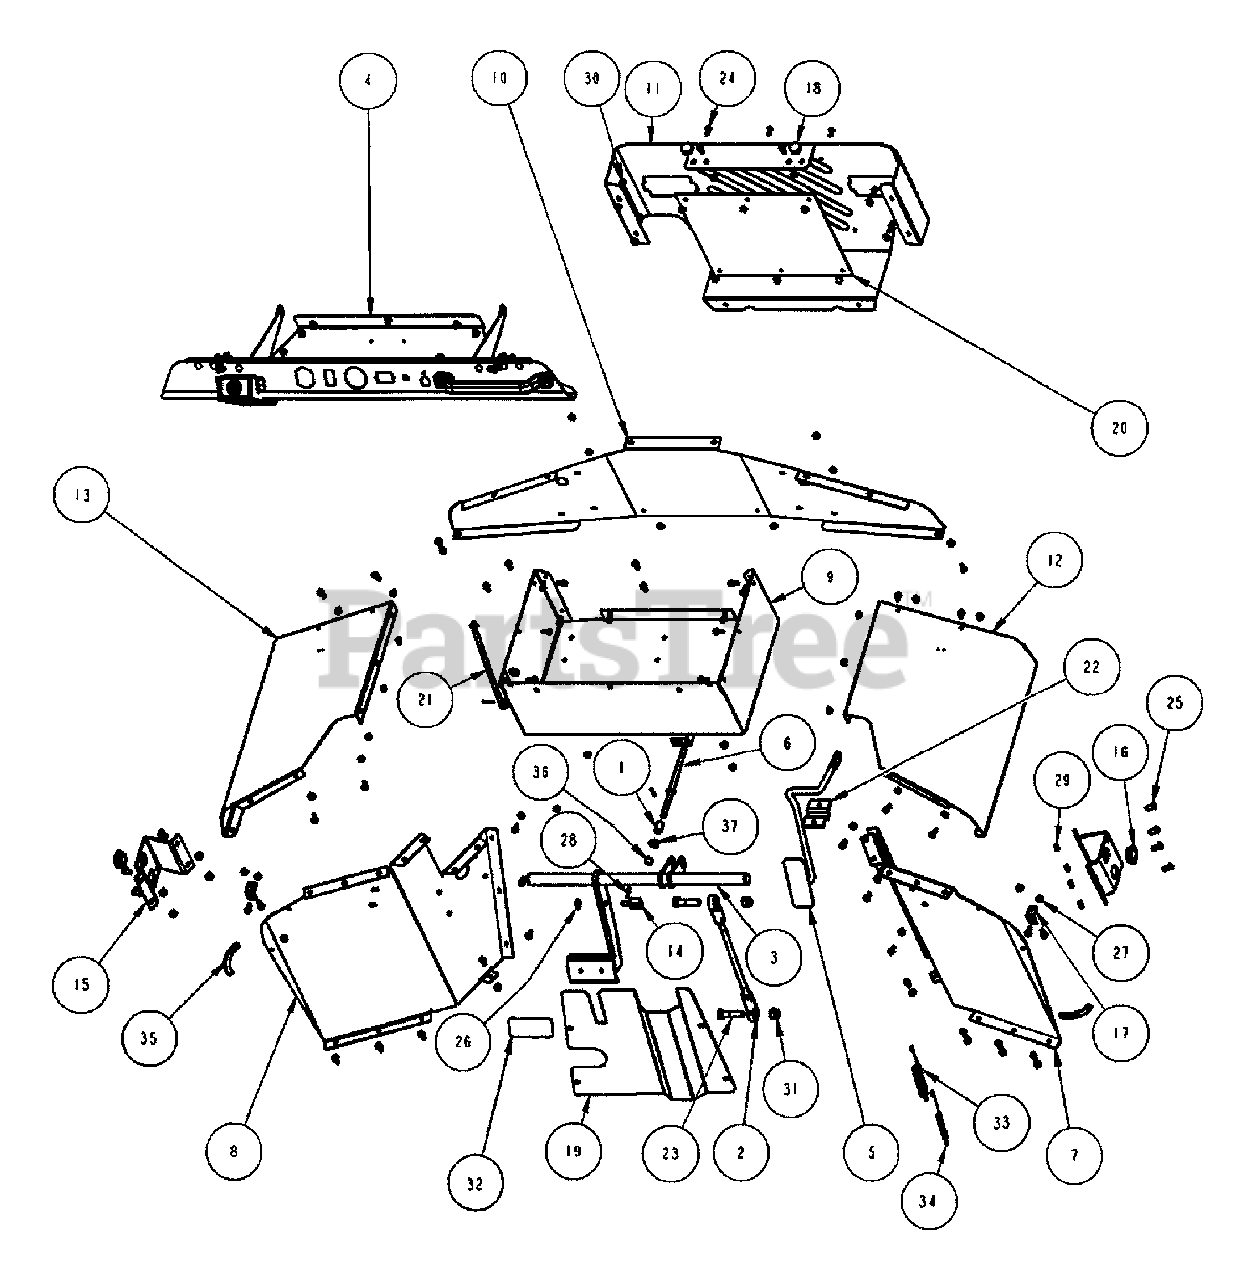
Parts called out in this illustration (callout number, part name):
1	SPRING, .051 WD X .46 OD X 2FL
2	UPPER BRAKE ROD ASSEMBLY
3	WELDMENT, CVT BRAKE PEDAL
4	DASH GROUP
5	WELDMENT, THROTTLE PEDAL
6	WELDMENT, BRAKE SWITCH ROD
7	FIREWALL, RH
8	FIREWALL, LH
9	TOOLBOX
10	GRILLE, INNER
11	GRILLE, OUTER
12	FENDER,RH
13	FENDER, LH
14	SWIVEL, 3/8 W/THRU HOLE
15	BRAKE SUPPORT BRACKET
16	BEARING, 1 IN.ID
17	BRACE, CORNER FENDER
18	BUMPER, ROUND RUBBER
19	PEDAL SHIELD
20	SCREEN, PERF. METAL
21	PROP ROD, HOOD
22	THROTTLE PIVOT BRACKET
23	HHCS, 5/16-18 X 2.00 YZ
24	PHST, 1/4-20 X 5/8 TORX
25	RHSSNB, 5/16-18 X 3/4 GR5 YZ
26	WASHER, .375 X .875 X.083
27	HFLN, 1/4-20
28	COTTER PIN, 1/8 X 3/4 YZ
29	FLN 5/16-18 YZ
30	HFLS, 1/4-20 X 5/8
31	NUT, 1/2-13, LIGHT, NYLOCK
32	PEDAL GRIP
33	SPRING, THROTTLE PEDAL RETURN
34	SPRING, INNER THROTTLE RETURN
35	EDGE TRIM, 4-1/2 INCH
36	BUSHING, FLG-.38 X .625 X .62
37	FLAT WASHER, 3/8 X .075
